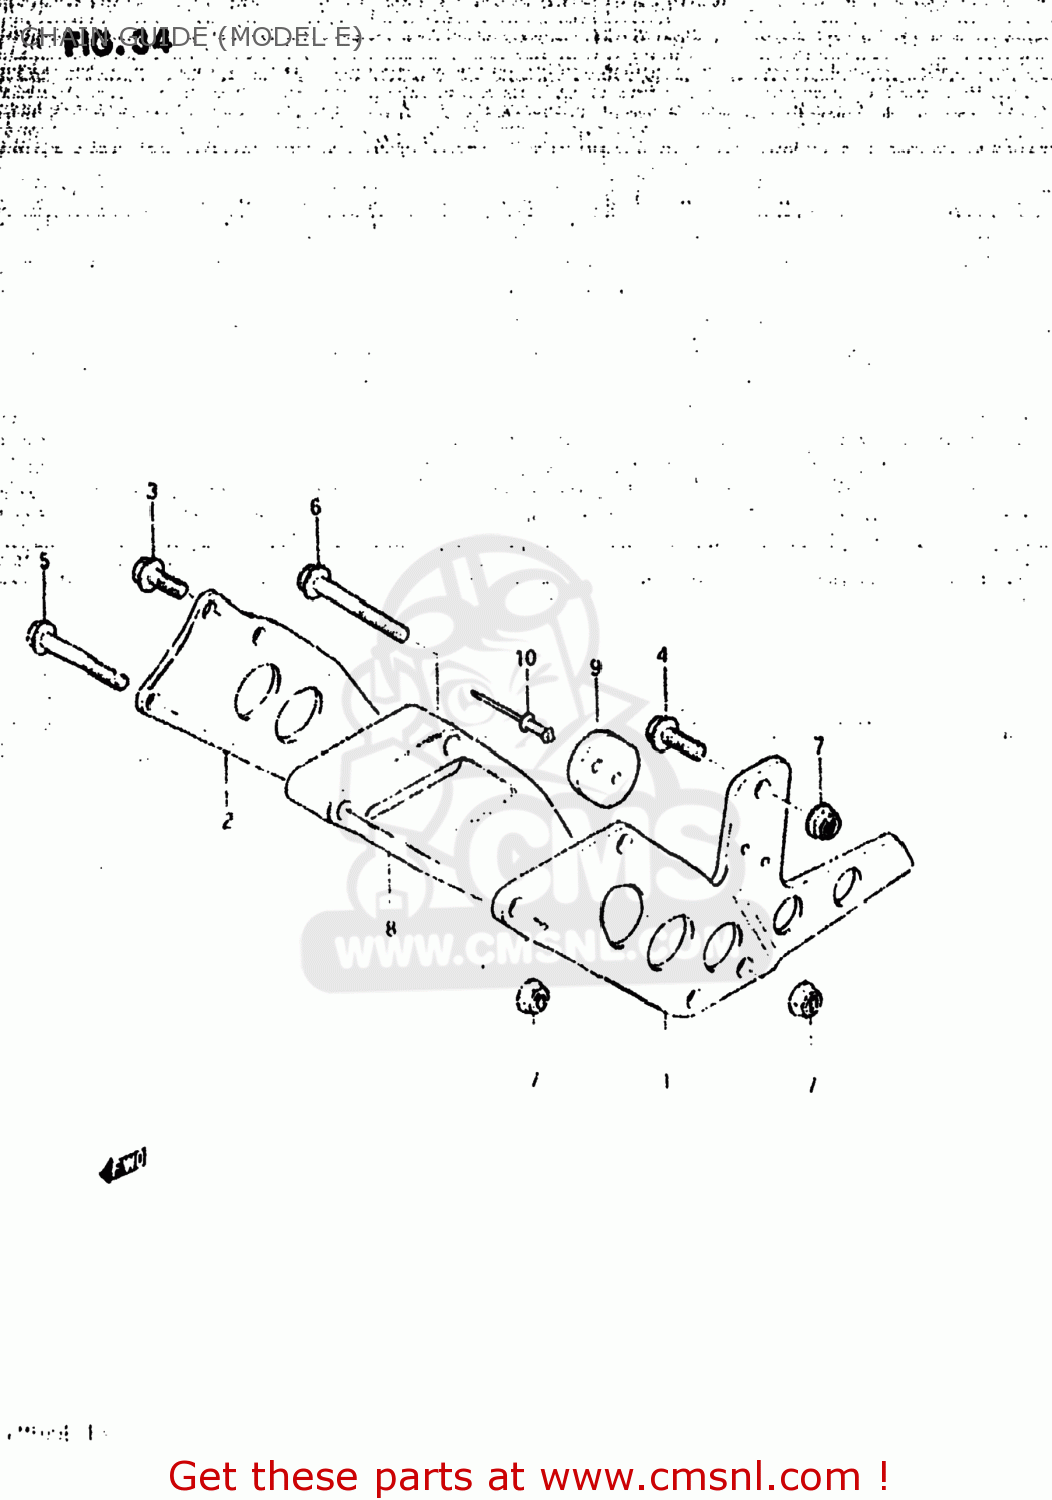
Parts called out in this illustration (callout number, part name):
1	PLATE,CHAIN GUIDE,OUTER
2	PLATE,CHAIN GUIDE,INNER
3	BOLT
4	BOLT
5	BOLT
6	BOLT,UNDER
7	NUT
8	DEFENSE,CHAIN GUIDE
9	PAD,CHAIN GUIDE
10	RIVET
